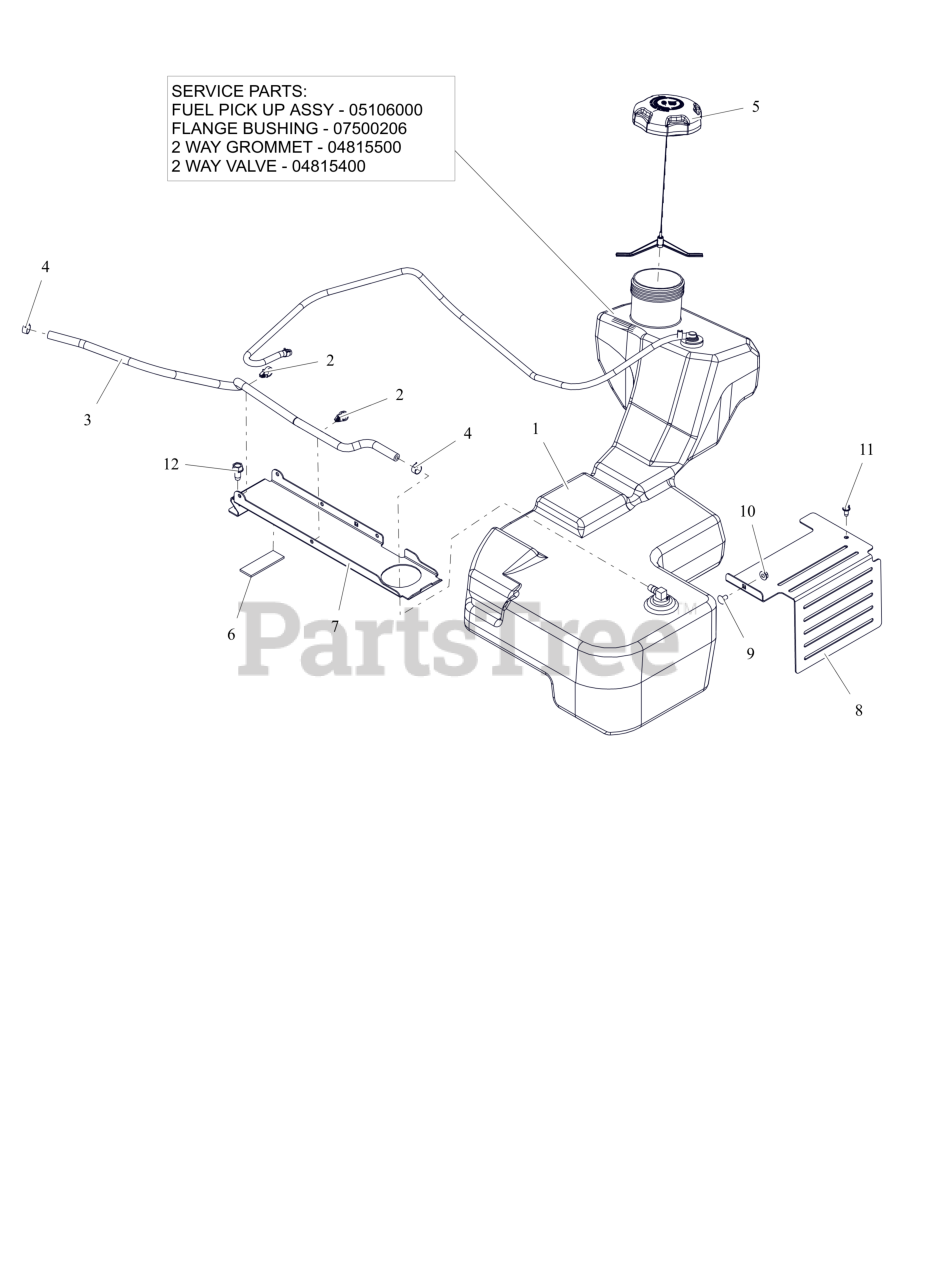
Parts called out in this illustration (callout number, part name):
1	ASM, FUEL TANK-HD
1	ASM, HD FUEL PICK-UP
1	BSHG-FLG .375X1.062X.625 NITR
1	GROMMET, 2-WAY
1	VALVE, 2-WAY
2	ROUTING CLIP (1/2" ID)
3	HOSE, .25 LOW-PERM BULK GAS
4	CLAMP, FUEL LINE
5	CAP, FUEL - 3.50 RATCHET INLET VENT
6	PAD,RBR 1.0"X3.0" W/ADHESIVE
7	BRKT, FUEL TANK HOLD DOWN
8	GUARD, TRANSAXLE FAN LH (BLACK)
9	BLT, RHSSN.25-20X.500 G5 ZCC
10	NUT-LK-CTR-FLG .25-20 ZC120
11	SCR-TAP .25-20X.50 HWH ZCC
12	SCR,TAP .375-16X.75 HWH TR ZCC
